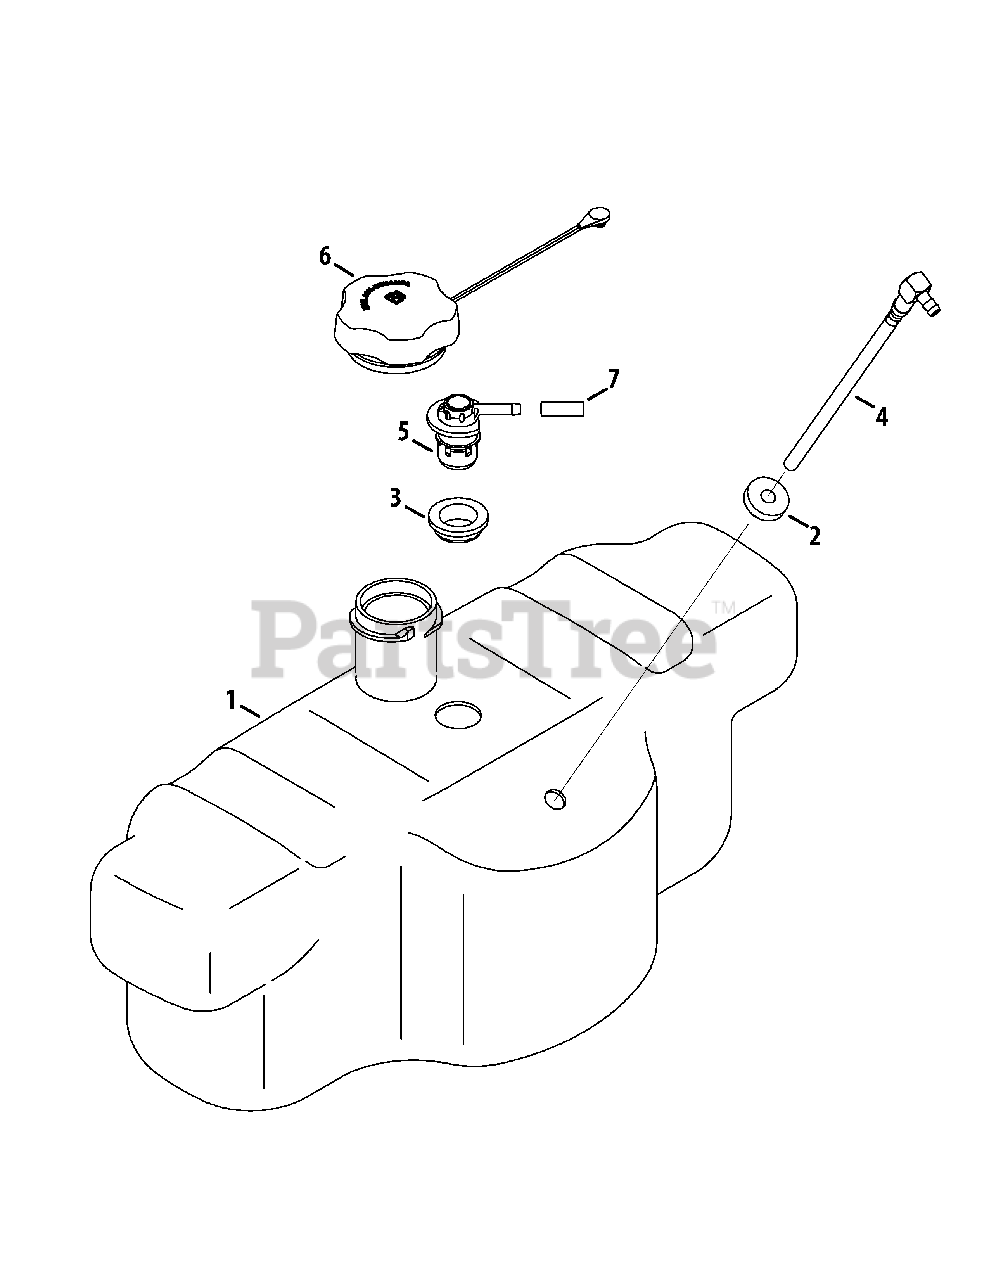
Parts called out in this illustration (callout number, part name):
1	Fuel Tank
2	Fuel Tank Bushing
3	Rubber Grommet
4	Fuel Pickup Fitting
5	Rollover Valve
6	Fuel Cap
